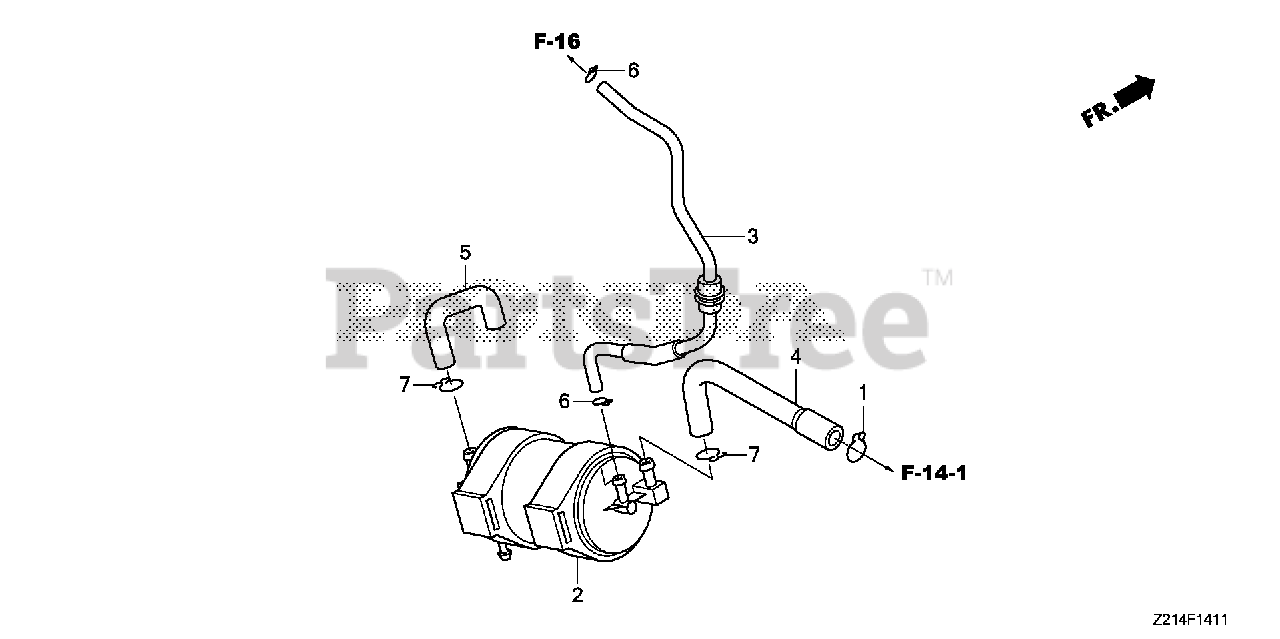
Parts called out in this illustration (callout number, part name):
1	CLIP, BREATHER TUBE
2	CANISTER ASSY.
3	TUBE CANISTER CHARGE
4	TUBE, CANISTER PURGE
5	TUBE, CANISTER AIR
6	CLIP, TUBE (B8)
7	CLIP, TUBE (B12)
